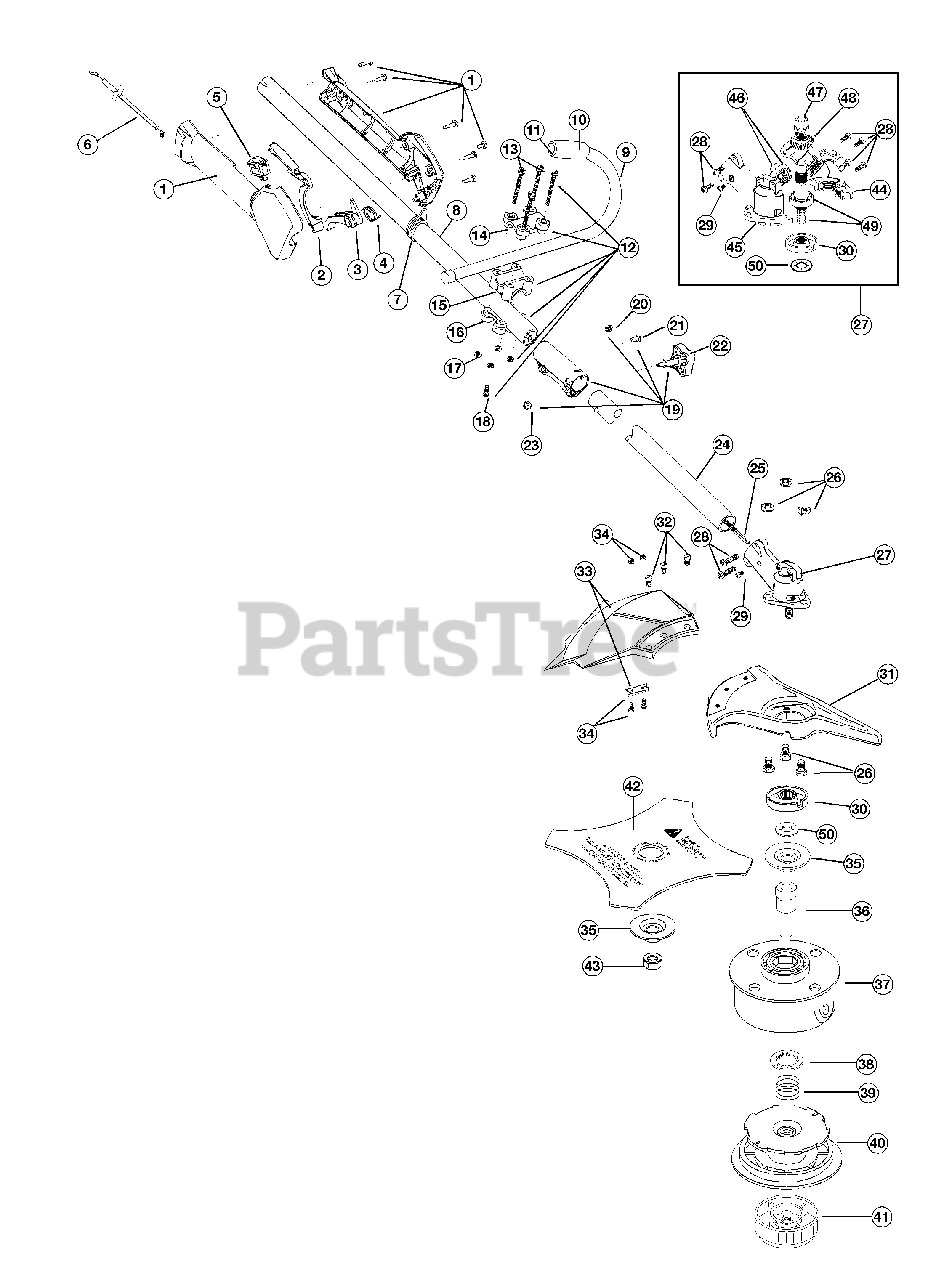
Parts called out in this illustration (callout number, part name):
1	Throttle Housing & Trigger Assembly
2	Throttle Trigger Lock-Out
3	Throttle Trigger
4	Throttle Trigger Spring
5	Switch Assembly
6	Throttle Cable
7	Harness Clip
8	Upper Drive Shaft Housing Assembly
9	J-Handle Assembly
11	Tube Closure
12	Handle Bracket Assembly
14	Upper Handle Clamp
15	Middle Handle Clamp
16	Lower Handle Clamp
18	Anti-Rotation Screw
19	Split-Boom Coupler
22	Adjustment Knob
23	Knob Retaining Nut
24	Lower Drive Shaft Housing Assembly
25	Lower Flexible Drive Shaft
26	Shield Mount Screw Assembly
27	2 piece Gearbox Assembly
28	Gearbox Mounting Hardware
29	Anti-Rotation Screw
30	Blade Driver
31	Blade Shield/Shield Mount
32	Shield Mounting Screw
33	Shield and Blade Assembly
34	Blade Assembly
35	Retaining Washer
36	Spool Shaft
37	Outer Spool and Eyelet Assembly
38	Retainer
39	Spring
41	Bump Head Knob Assembly
42	4-Tooth Blade
43	Nut
44	Left Housing
45	Right Housing
46	Pinion Gear Assembly
47	Output Shaft Bushing
48	Output Shaft Gear
49	Output Shaft Assembly
50	Palnut
